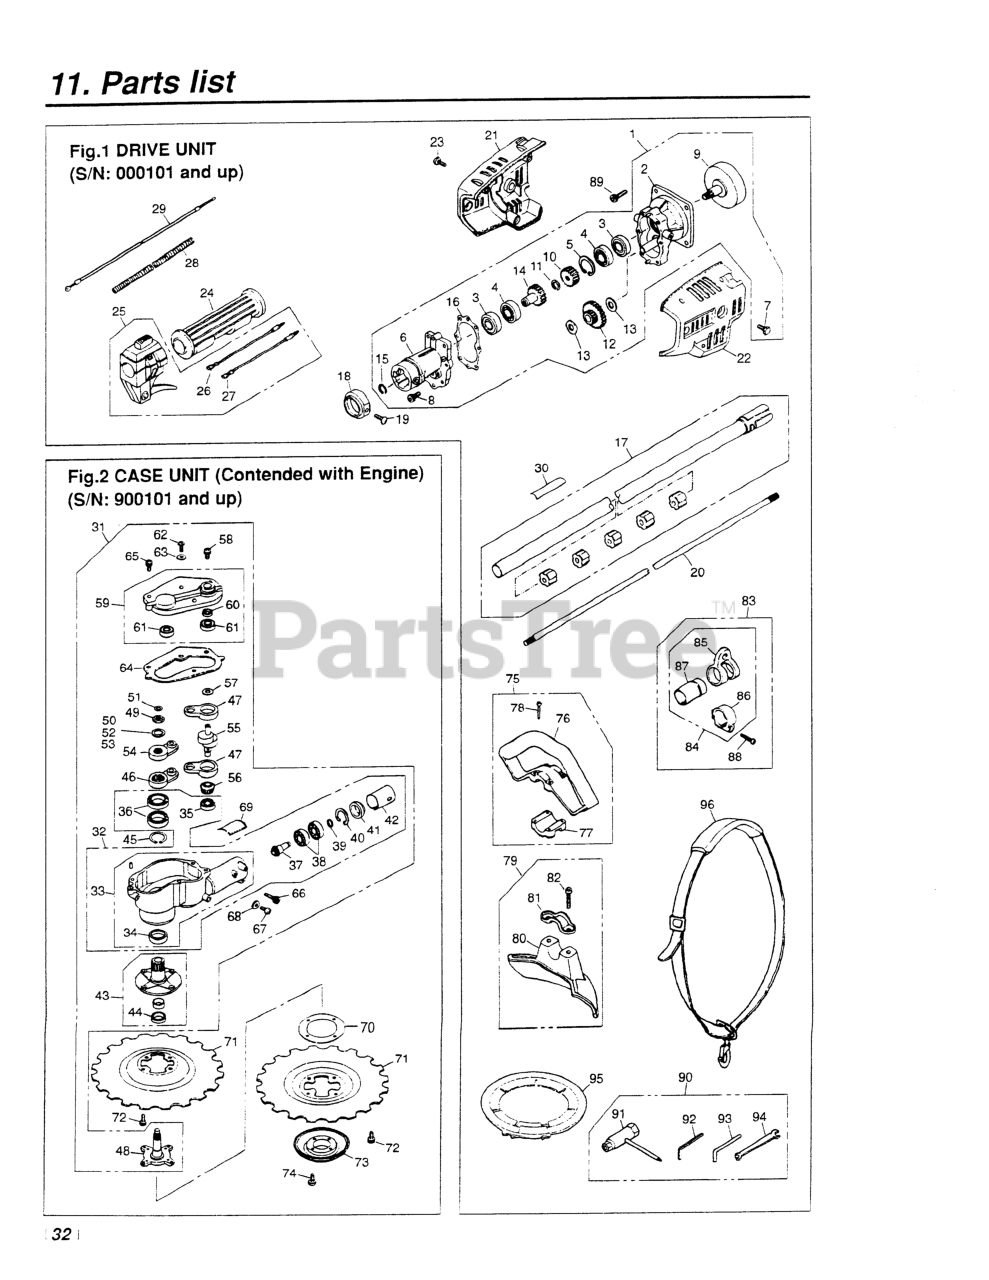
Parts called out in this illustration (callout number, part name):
1	MISSION ASSEMBLY
2	CASE, REAR COMP (RPLS -11101)
4	BEARING
5	RING, SNAP, M28 x 1.2
6	CASE, FRONT
7	BOLT, M6 x 8
8	BOLT, M5 X 20
9	DRUM
10	GEAR, PINION
11	RING, SNAP
12	GEAR (RPLS 3805-11330)
13	WASHER
14	GEAR, WHEEL
18	CAP
19	SCREW, M5 X 10
20	SHAFT
21	COVER, RIGHT (RPLS. -11510)
22	COVER, LEFT (RPLS -11520)
24	GRIP (RPLS 3577-32140 & 3220-
26	CORD (A), BLACK
27	CORD (B), RED
28	TUBE (RPLS 4900-72141)
29	CABLE COMP
30	PLATE, NAME (SGCX2600S)
31	CUTTERCASE ASSEMBLY
32	CUTTERCASE (RPLS -98100)
33	CASE, CUTTER (RPLS -13100)
34	SEAL, OIL
36	BEARING
37	PINION
38	BEARING (RPLS T3403-13510)
39	RING, SNAP
40	RING, SNAP, M26 X 1.2
41	PACKING
42	SPACER (RPLS -13950)
43	SHAFT, OUTER-C
44	SEAL, OIL
45	RING, SNAP, M20 x 1.2
46	ARM, LOWER (RPLS -13411)
48	SHAFT, INNER
50	SHIM, 0.3t
52	SHIM, 0.2T
53	SHIM, 0.1t
54	ARM, UPPER (RPLS -13611)
55	CRANKSHAFT (RPLS -13710)
56	GEAR
57	WASHER, M8 x 1.2
58	BOLT
59	COVER COMP
60	SEAL, OIL
62	SCREW, M6 x 10
63	WASHER, M6 x .8
64	GASKET
65	BOLT, M5 x 20
66	BOLT, M6 x 1.35
67	SCREW, M5 x 14
68	WASHER, M5x.8(RPLS 01624-20508
69	LABEL, CAUTION
72	BOLT, M6 x 8
73	STABILIZER (RPLS -15151)
74	SCREW, M5 X 8
75	HANDLE ASSEMBLY
76	HANDLE
78	SCREW, M5 x 35
79	GUARD ASSY (RPLS -24000)
80	GUARD (RPLS -24110)
81	CLAMP (REPLACES 5807-24120)
82	BOLT, M6 x 1.30
83	HANGER ASSEMBLY
84	HANGER COMPLETE
85	HANGER
86	CLAMP
87	SLEEVE
88	SCREW, M5 x 25
89	BOLT, M6 x 20
90	TOOL SET (SGCZ2500S)
91	SOCKET
92	WRENCH (TOOL)
93	WRENCH (TOOL)
94	SPANNER, 8 X 10 (RPLS 2540- )
95	COVER (REPLACES D0041) ACC.
